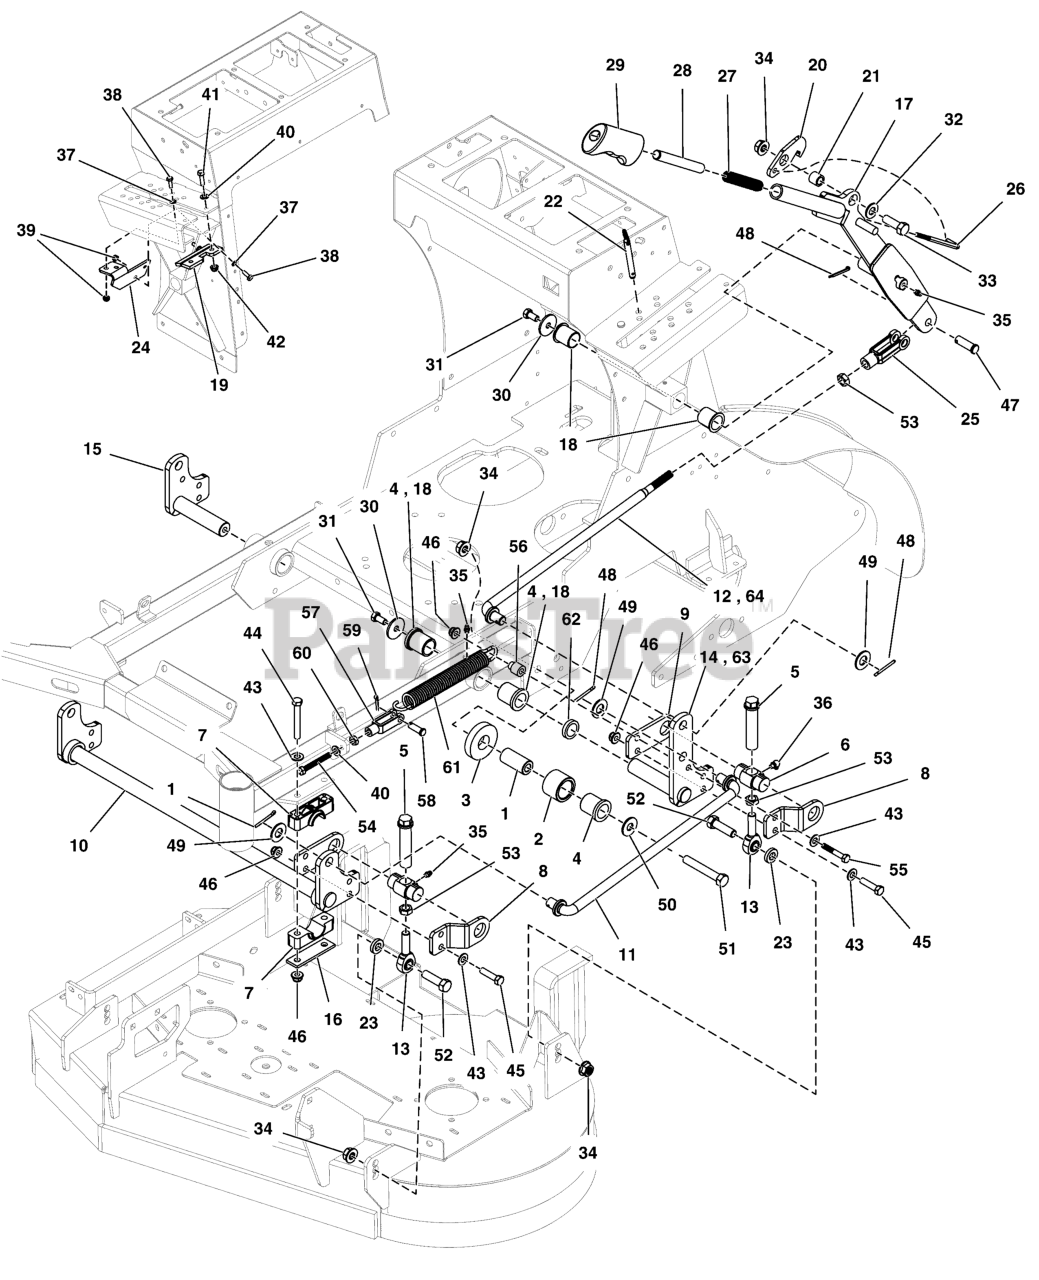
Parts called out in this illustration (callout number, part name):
1	SPACER, .52 X 1.00 X 2.09 - SS
2	ROLLER, DECK HEIGHT
3	WASHER, FRICTION
4	BUSHING, FLANGE
5	ADJUSTER, HEIGHT
6	PIVOT, DECK LIFT TRUNION, GREASABLE
7	PIVOT BLOCK, PLASTIC
8	BRACKET, OUTER TRUNION MNT - BLK
9	BRACKET, INNER TRUNION MNT - BLK
10	WELD, DECK LIFT SHAFT, SRSZ1 - BLK
11	ROD, DECK LIFT TIMING, SRSZ1
12	ROD, MAIN DECK LIFT, SRSZ1
13	BALL JOINT, 1/2-20, RH, MALE, METAL RACE
14	WELD, REAR LIFT PIVOT, LH - BLK
15	WELD, REAR LIFT PIVOT, RH - BLK
16	PLATE, PIVOT BLOCK SUPPORT - BLK
17	WELD, DECK LIFT, STAND ON - BLK
18	BUSHING, 1.00 X 1.13 X 1.38, Plastic
19	PLATE, LATCH GUIDE - BLK
20	PLATE, LATCH, PUSH BUTTON LIFT - BLK
21	SPACER, .50 X .75 X .66, CZ
22	PIN, HITCH, 3/8" DIA X 2.5" EL, CZ
23	WASHER, .515 X 1.00 X .25", CZ
24	PLATE, BRACKET, DECK LIFT SUPPORT - BLK
25	CLEVIS, 1/2-20, STEEL, CLEAR ZINC
26	ROD, DECK LIFT LATCH
27	SPRING-COMP 0.715ODX 03.85 LG
28	BUTTON, PUSH, DECK LIFT, THREADED
29	GRIP,LIFT LEVER
30	WASHER, .390 X 1.50 X .109, YZ
31	BOLT, 3/8-16 X 3/4, PLT W/PATCH
32	WASHER, 1/2 SAE
33	BOLT, 1/2-13 X 1-1/2 GD5 CZ
34	NUT, Hex Flange, Nylock, 1/2-13
35	GREASE FITTING, 1/4-28 Straight
36	GREASE FITTING, 1/4-28 STRAIGHT, 90 DEGREE
37	WASHER, 1/4 SAE
38	BOLT, 1/4"-20 X 3/4" GD5 YZ
39	NUT, 1/4-20 Hex Nylock Flange
40	WASHER, 5/16" SAE
41	BOLT, 5/16-18 X 1" GRD5 YZ
42	NUT, 5/16-18 HEX NYLOCK FLANGE NUT
43	WASHER, 3/8 SAE
44	BOLT, 3/8-16 X 2-3/4" GD5 CZ
45	BOLT, 3/8-16 X 1-1/2" GD5 CZ
46	NUT, 3/8 - 16 HEX NYLOCK FLANGE
47	PIN, CLEVIS, 1/2 X 1-1/2, PLATED
48	PIN, COTTER, 1/8 X 1-1/4
49	WASHER, 5/8" SAE
50	WASHER, 1/2" USSZ
51	BOLT, 1/2-13 X 3-1/4, HEX HD, GD5, CZ (SV)
52	BOLT, 1/2-13 X 1-3/4 GD5 CZ
53	NUT, 1/2-20 Hex Jam
54	BOLT, 5/16-18 X 2-1/2 GD5 TFL, CZ
55	BOLT, 3/8-16 X 2, GD5, CZ
56	SPACER,3/8X3/4X15/16
57	CLEVIS, 5/16-18, 3/8 PIN HOLE, CLR ZINC
58	PIN, CLEVIS, 3/8 X 1-1/8, PLATED
59	PIN, 3/32 X 0.750, COT, ZINC/CLEAR
60	NUT, 5/16-18 HEX JAM
61	SPRING-EXTN 1.12 ODX 09.06 LG .177 ECOAT
62	SPACER, 1.02 x 1.56 x .50
63	WELD, REAR LIFT PIVOT, LH - BLK
64	ROD, MAIN DECK LIFT, 14.00
